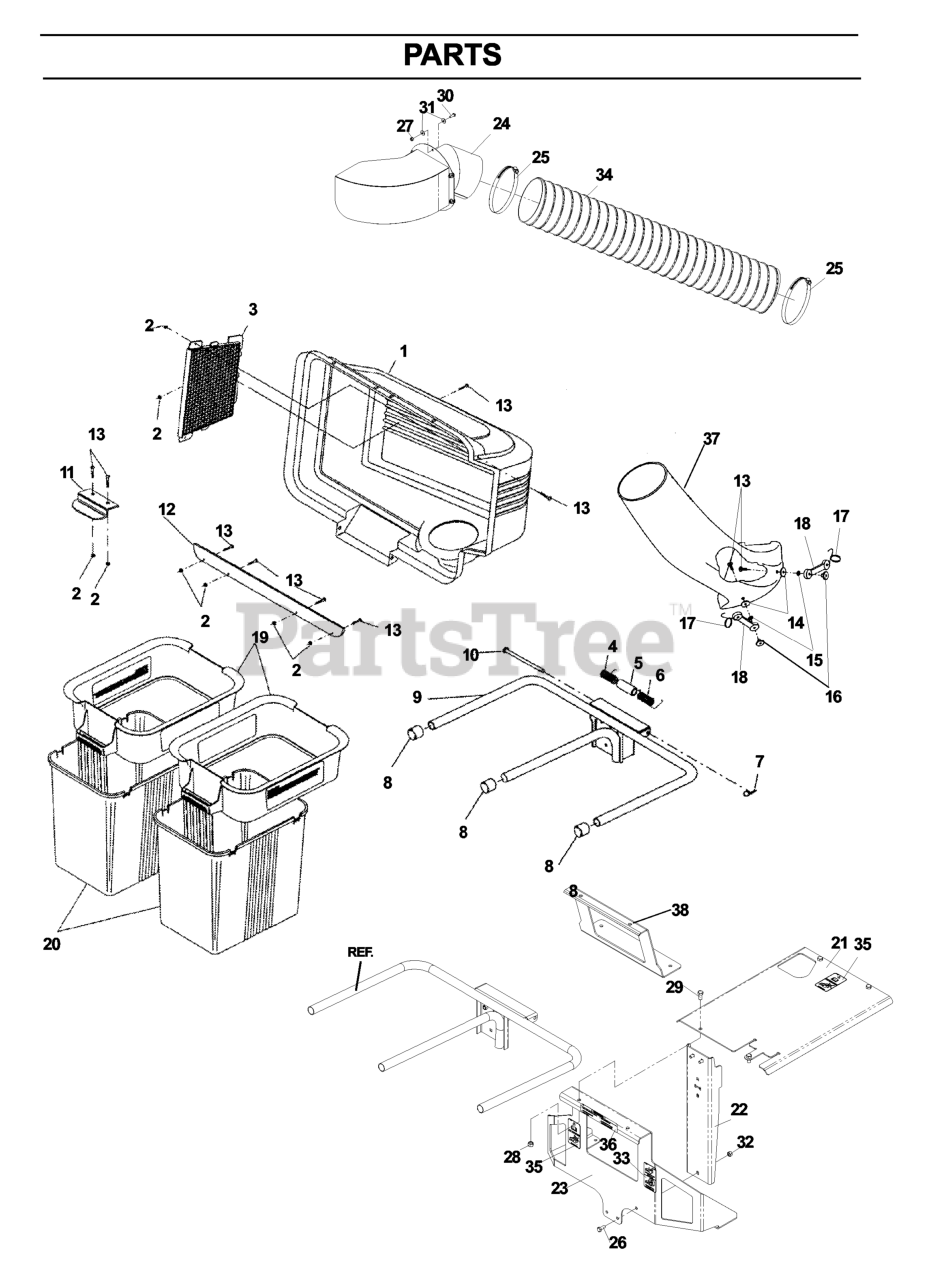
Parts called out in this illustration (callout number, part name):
2	NUT, 3/10-24, CROWNLOCK
3	COVER SCREEN
4	SPRING COVER LH
5	SPACER.COVER.BAGGER
6	SPRING COVER RH
7	RETAINER-SPRNG RB
8	PLUG, TUBING END
9	FRAME.ASM.BAGGER.2BIN.QC42B
10	HINGE PIN
11	LATCH CER38
12	STRIP.REINFORCE.BAGGER.2BIN.BL
13	SCREW
15	LOCKWASHER #10
16	WELDNUT
17	HOOK LATCH
18	RUBBER LATCH
19	CONTAINER TOP
20	CONTAINER BOTTOM
21	PLATE, W/DECAL
23	REAR BRACKET W/ DECALS
25	HOSE CLAMP 4-1/8 TO 7"
26	HCS 5/16C X 3/4
27	NUT.1/4-20.HEX.NYLOC.ZD
28	NUT 3/8-16 NYLOC
29	SCREW 3/8C X 3/4 HEX CAP
30	HCS 1/4C X 3/4 HCS
31	WASHER 1/4 FLAT
32	NUT 5/16 NYLOC
33	DECAL, PAYLOAD/GASOLINE
35	DECAL, UTILITY BOX WARNING
36	DECAL, UTILITY BOX PAYLOAD
37	LOWER BOOT 42
38	FRT BRACKET TOOL BOX, PAINTED
539976988	HAIRPIN #2
539977703	CLEVIS PIN 3/8 X 1 1/8
